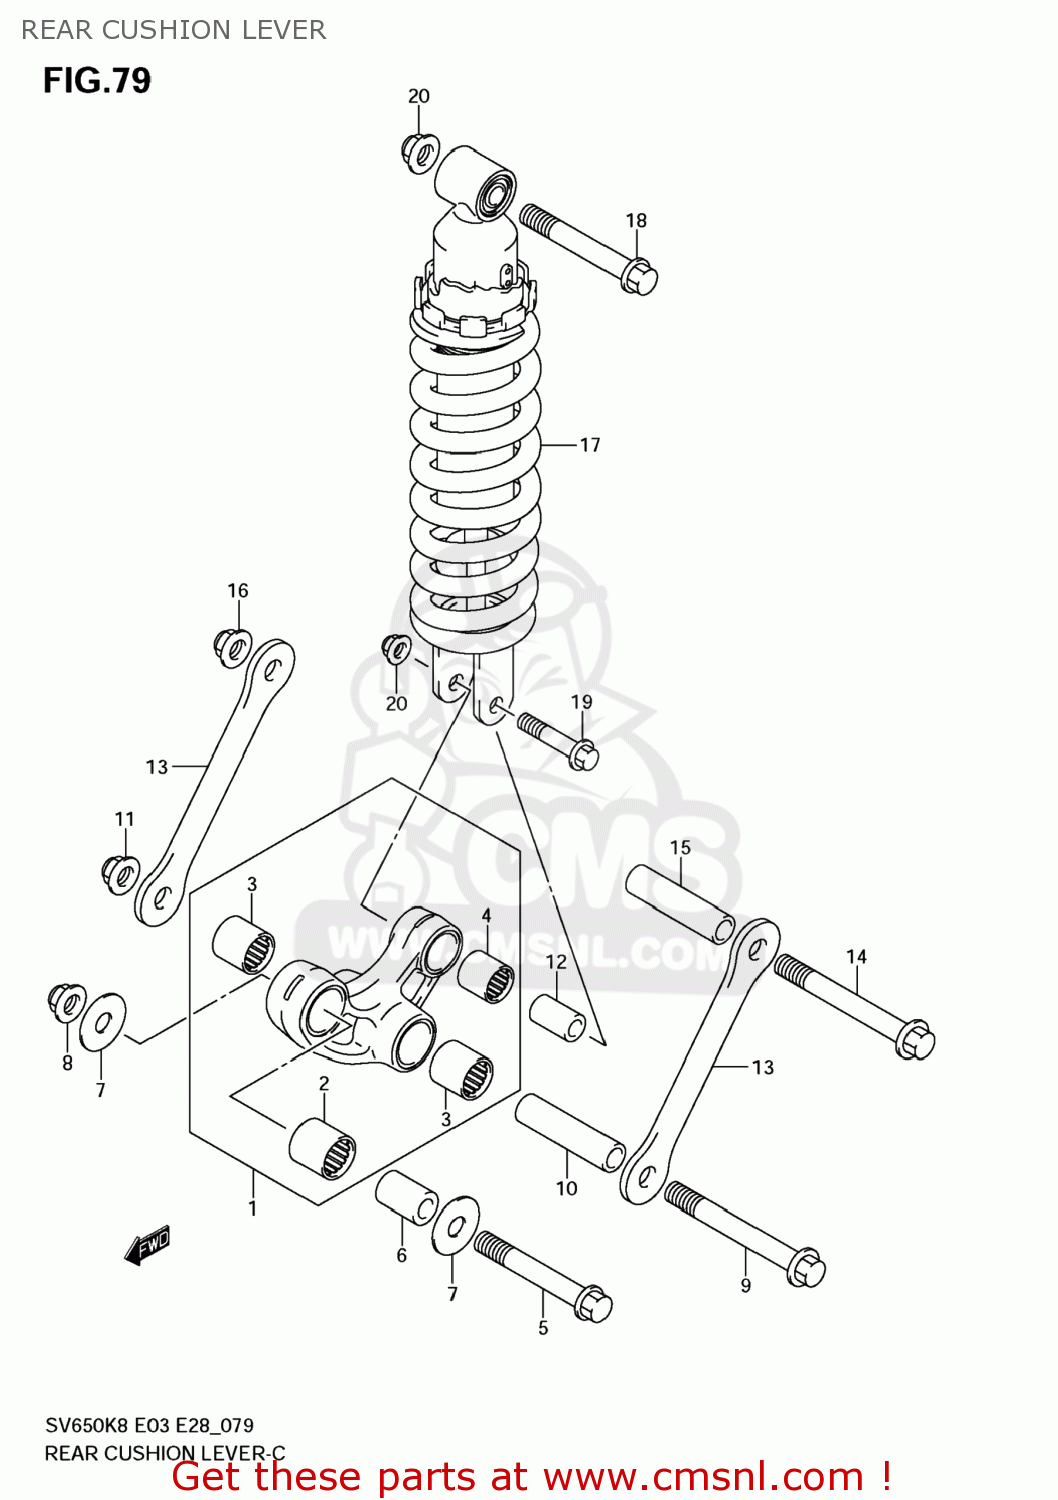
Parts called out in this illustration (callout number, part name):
1	LEVER SET,RR CUSHION
2	BEARING(20X27X30)
3	BEARING(17X24X20)
4	BEARING(17X24X26)
5	BOLT,RR CUSHION LEVER FR
6	SPACER,RR CUSHION LEVER FR
7	WASHER(12X34X1)
8	NUT
9	BOLT(12X96)
10	SPACER,RR CUSHION LEVER CTR
11	NUT
12	SPACER,RR CUSHION LEVER
13	ROD,RR CUSHION LEVER
14	BOLT(12X96)
15	SPACER,RR CUSHION LEVER CTR
16	NUT
17	ABSORBER ASSY,RR SHOCK(WHITE)
18	BOLT(10X70)
19	BOLT(10X48)
20	NUT
